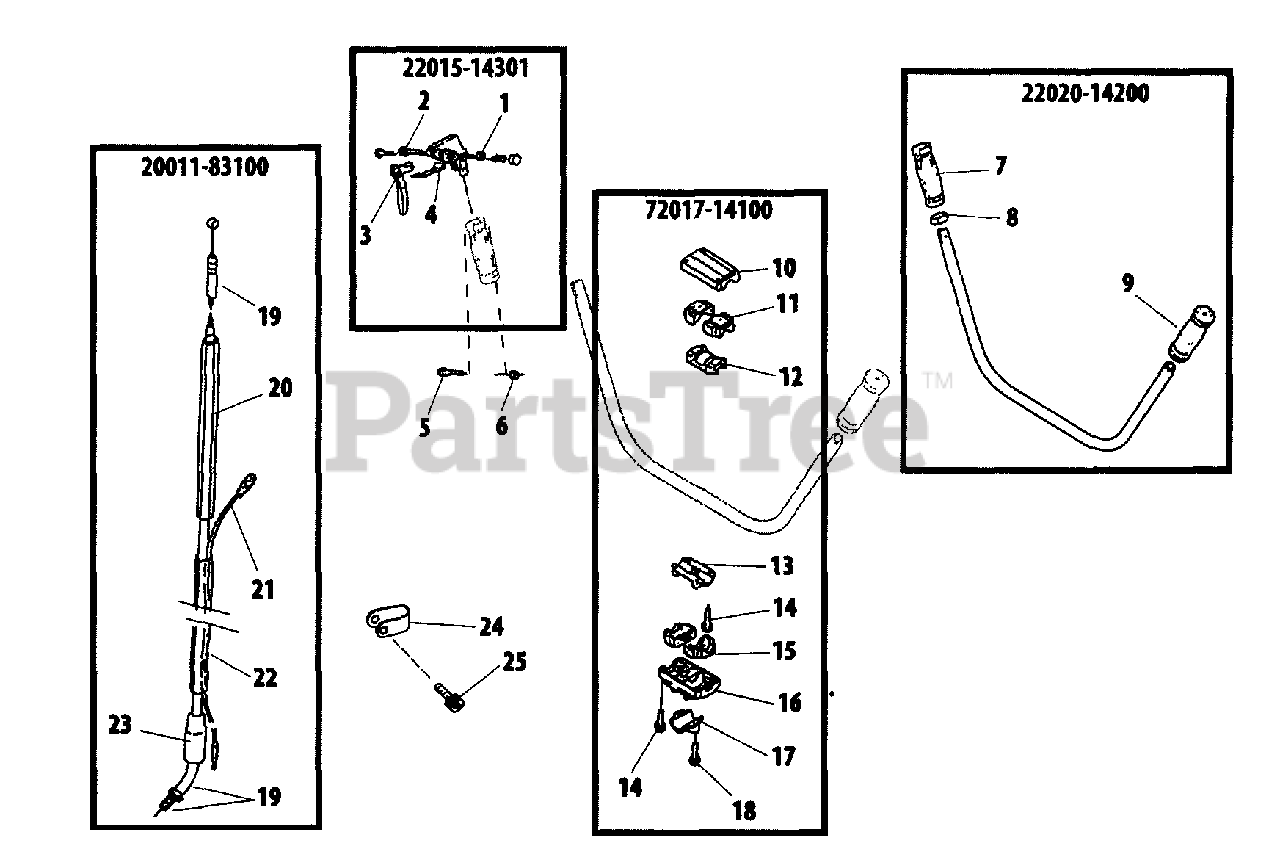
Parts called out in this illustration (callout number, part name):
1	LOCKNUT - 5
2	BOLT
3	TRIGGER, THROTTLE
4	STOPPER, THROTTLE TRIGGER
5	BOLT M4×24
6	NUT, NYLON M4
7	GRIP, RIGHT
8	HOLDER, THROTTLE CABLE
9	GRIP, LEFT
10	CLAMP, UPPER
11	CUSHION, UPPER
12	CLAMP, UPPER
13	CLAMP, LOWER
14	BOLT M5×25
15	CUSHION, LOWER
16	BRACKET, HANDLE Ø28
17	CLAMP, LOWER Ø28
18	SCREW M6×25
19	CABLE, THROTTLE
20	TUBE, THROTTLE CABLE
21	LEAD - GROUND
22	TUBE, PROTECTIVE
23	CAP, CARBURETOR
24	CLAMP
25	BOLT M4×12
20011-83100	THROTTLE CONTROL ASSY
22015-14301	THROTTLE CONTROL ASSY
22020-14200	HANDLEBAR ASSY
72017-14100	BRACKET KIT, HANDLEBAR
